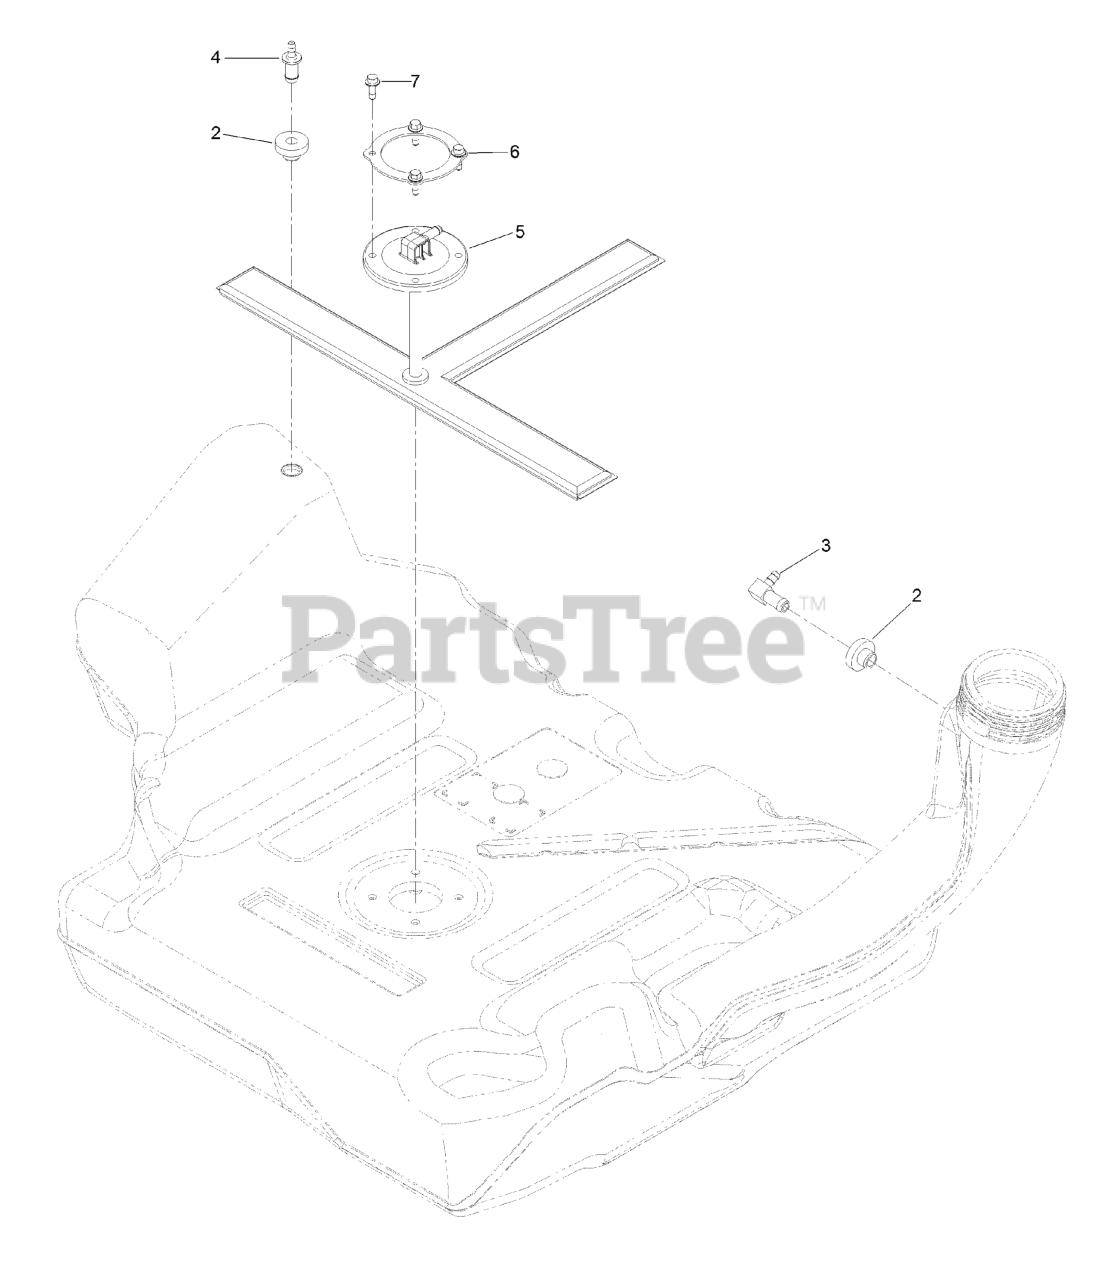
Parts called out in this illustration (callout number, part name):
2	BUSHING
3	FITTING-90 DEG
4	FITTING-ORIFICE, STRAIGHT
5	PICKUP-FUEL
6	RING-RETAINER
